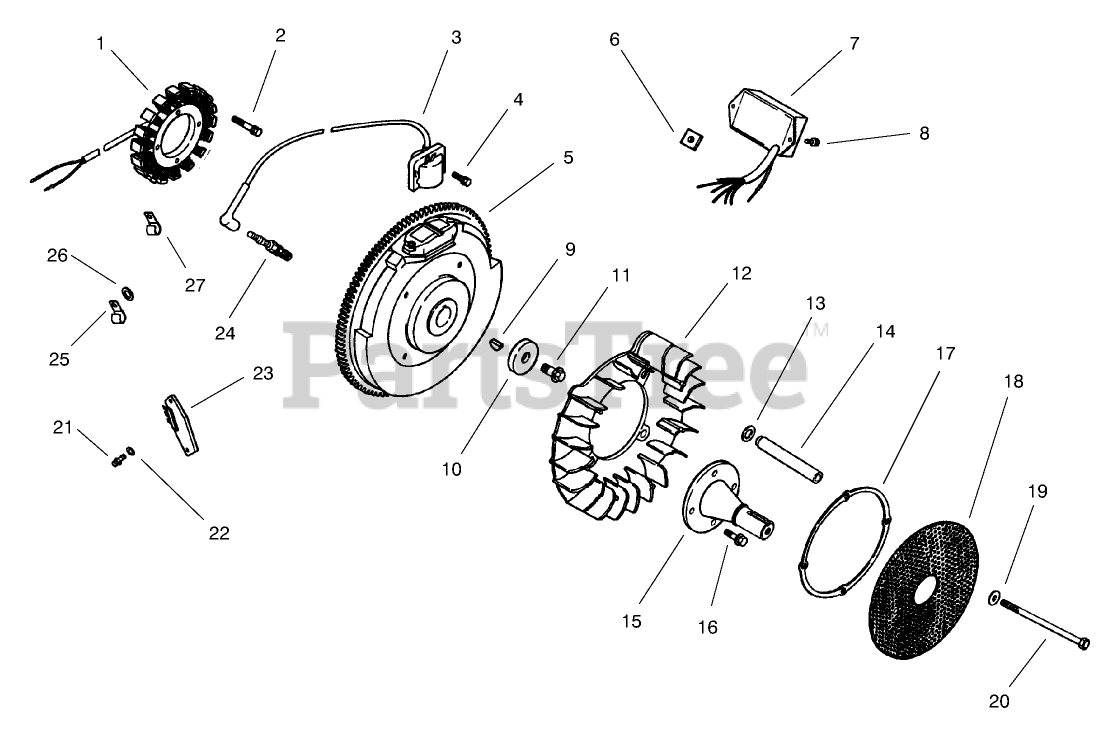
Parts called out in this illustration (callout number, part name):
1	Stator Kit, 15 Amp
2	Screw
3	Module-Ignition
4	Screw-HSH
5	Flywheel
6	Nut INCL W/Blower Hsng (Only On: 72103)
7	Module, speed adv.
8	Screw
9	Key
10	Washer
11	Screw
12	Fan (Only On: 72103, 72083)
13	Washer, sping
14	Spacer
15	Shaft, front drive
16	Screw M8x1.25x22 (Only On: 72042, 72043, 72062, 72063)
17	Ring-Support
18	Screen-Grass
19	Washer
20	Screw-Hex
21	Screw
22	Washer
23	Rectifier-Regulator
24	Spark Plug
25	Clip-Cable (Only On: 72103)
26	Washer
27	Clip
